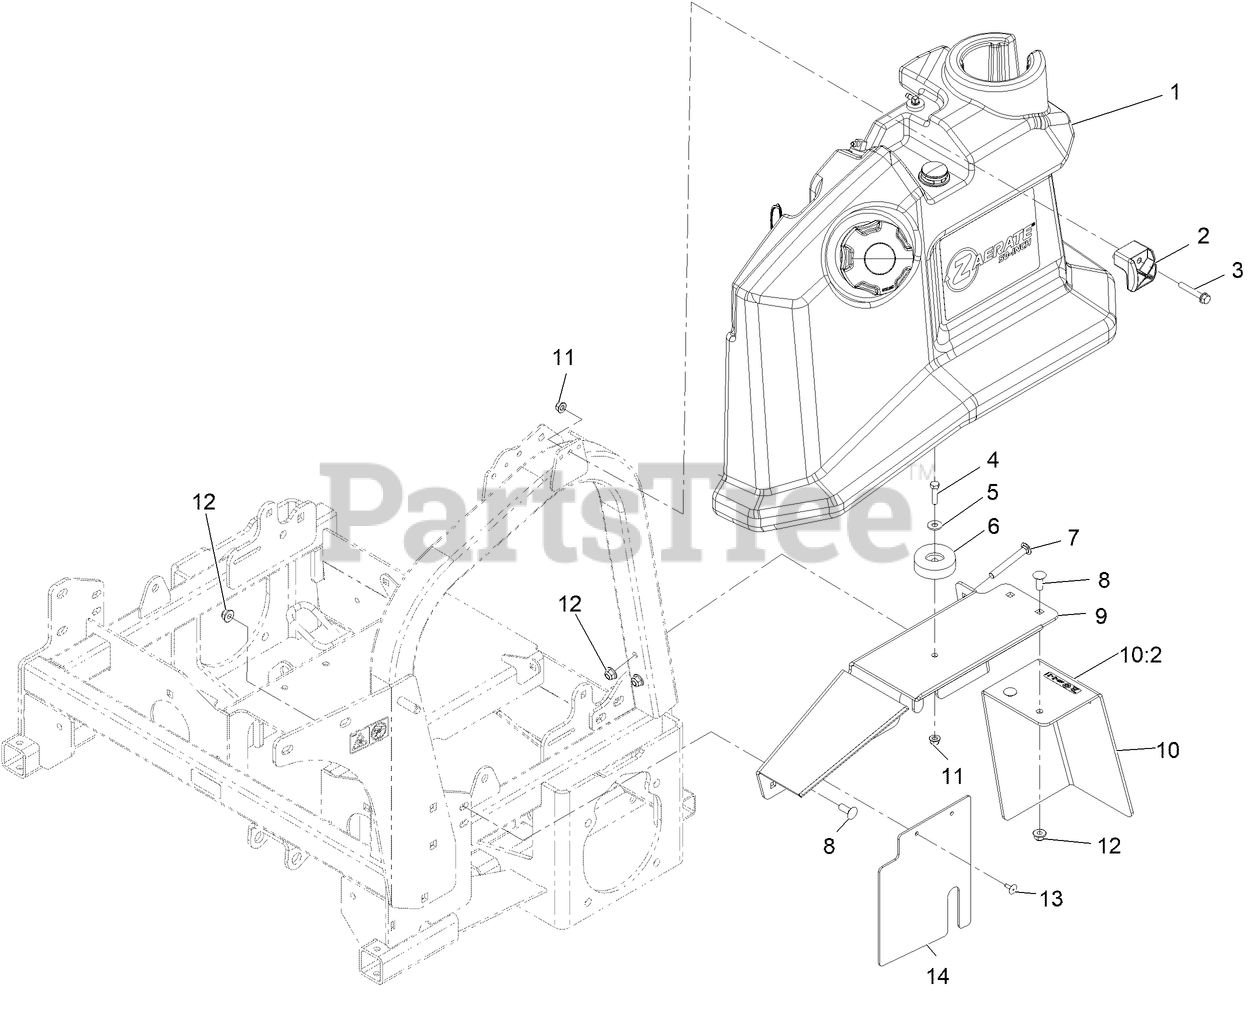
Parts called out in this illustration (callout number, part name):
1	FUEL TANK ASM W/DECAL
3	SCREW-HHF
4	SCREW-HH
5	WASHER-FLAT
6	BUMPER-RECESS
7	SCREW-CARR
8	SCREW-CARR
9	BRACKET-FUEL TANK MOUNT, LOWER
10	LH FENDER ASM W/DECAL
10:2	DECAL-TORQUE, WHEEL NUT
11	NUT-HF, NI
12	NUT-HF, NI
13	RIVET-POP
14	FLAP-COVER, SIDE
